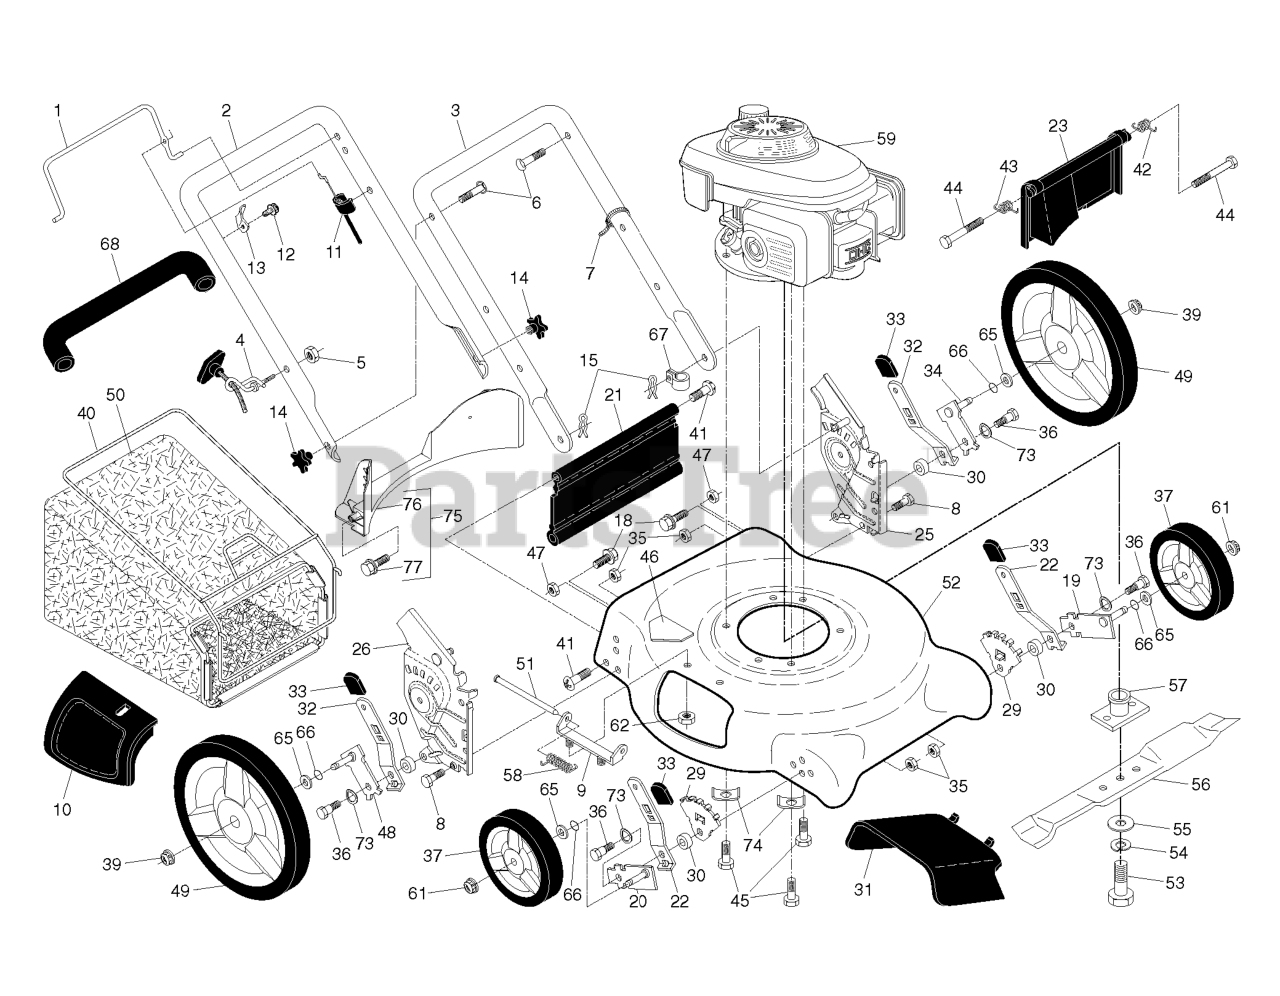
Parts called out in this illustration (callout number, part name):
1	BAIL.MZR.STD.ORANGE
2	UPPERHANDLE(INCLUDES FOAMGRIP)
3	HANDLE.LOWER.GREY
4	RB GUIDE.ROPE.STD.BLK.ZIN WSL
5	NUT
6	BOLT, HANDLE 5/16-18X1.75
7	TIE GUIDE
8	BOLT.FIN.HEX.5/16-18X3/4
9	BRACKET.ASM.HOUSING.EZ.MUL
10	RP DOOR.MULCH.21".REAR.PUSH.GR
11	ENGINE ZONE CONTROL CABLE
13	BRACKET.UPSTOP.RT
14	KNOB.HANDLE.PLASTIC.STAR.BLACK
15	HAIRPIN COTTER
18	SCREW 1/4X20
19	AXLE ARM ASSY FRONT LH
20	AXLE ARM ASSY FRONT RH
21	RP_KIT.SKIRT.21 DOMED.W/LIP
22	SELECTOR SPRING, FRONT
23	REAR DOOR ASSY
25	RP BRKT.ASM.HAND.HW.21.LT.ORNG
26	RP BRKT.ASM.HAND.HW.21RT.ORNG
29	WHEEL ADJ BRACKET FRONT
30	SPACER.HEIGHT.ADJUSTER
31	DEFLECTOR.CLIPPING.21.GREY
32	SPRING.SEL.EXT.21.DOMED.12/14
34	AXLE ARM ASSY REAR LH
35	NUT.FLANGE.HEX.5/16X18.BLACK
36	SHOULDER BOLT 5/16-18
37	WHEEL & TIRES ASSY, FRONT
39	NUT.HEX.FLANGE.3/8-16.LOCKNUT
40	FRAME.BAG.21.REAR.DOMED.PUSH
41	HINGE SCREW
42	SPRING.LH.22.REAR.DOOR.EZ.EMPT
43	SPRING.RH.22.REAR.DOOR.EZ.
45	BOLT 3/8-16X1-1/8
46	DANGER DECAL
47	NUT.LOCK.5/16-18
48	AXLE ARM ASSY REAR RH
49	WHEEL ASSY
50	GBAG.2323247.SILVER
51	ROD.HINGE.COMBI-C
52	RP KIT.HSG.
53	SCREW, HEX HD 3/8-24 X 1-3/8
54	LOCKWASHER
55	WASHER,HARDEN
56	BLADE.21.PUSH/RWGD/FWGD
57	RP BLADE ADAPTER
58	TORSION SPRING
61	NUT.HEX.FLANGE.3/8-16.LO(3 2)
62	LOCKNUT.NYLOC.1/4-20
65	WASHER.FLAT.1/2
66	O-RING..070X.487.NEOPRENE
67	CLIP.CABLE.BLK
68	GRIP.HANDLE.FOAM
73	WASHER.CURVED.CYLINDRICAL
74	WASHER.ENGINE.BZP
75	KIT.BAFFLE.REAR.PLASTIC.21.RD
76	BAFFLE.REAR.PLASTIC.21.RD.ECON
77	SCREW.HX.13X.750
